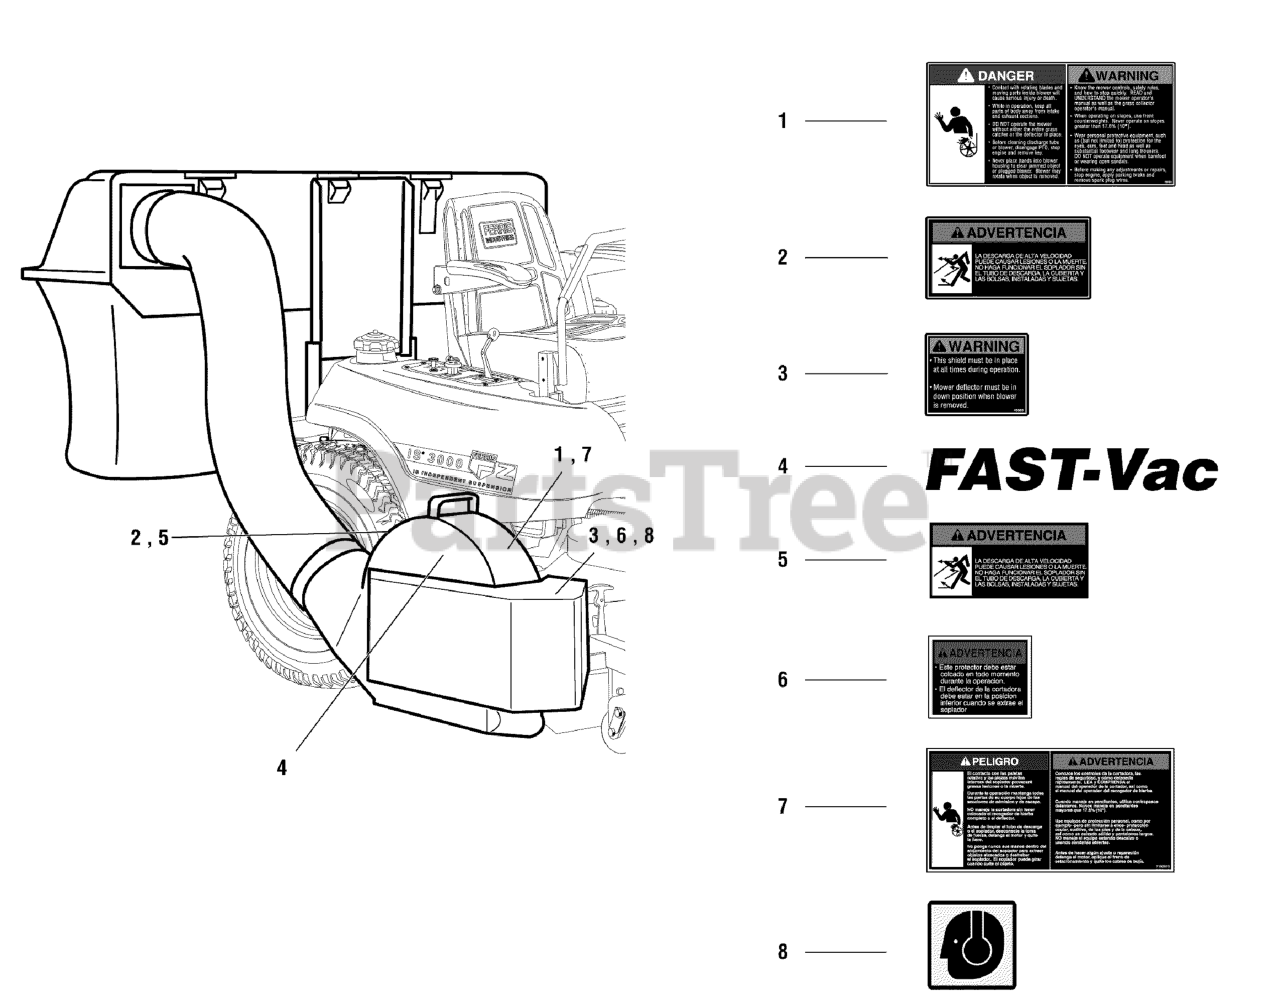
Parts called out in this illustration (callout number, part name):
1	DECAL, Danger/Warning
2	DECAL, Warning-Blower
3	DECAL, Warning-Shield
4	DECAL, Fast-Vac
5	DECAL, Danger, Catcher, SP
6	DECAL, Danger, Catcher, SP
7	DECAL, Danger, Fast-Vac, SP
8	DECAL, Ear Protection
